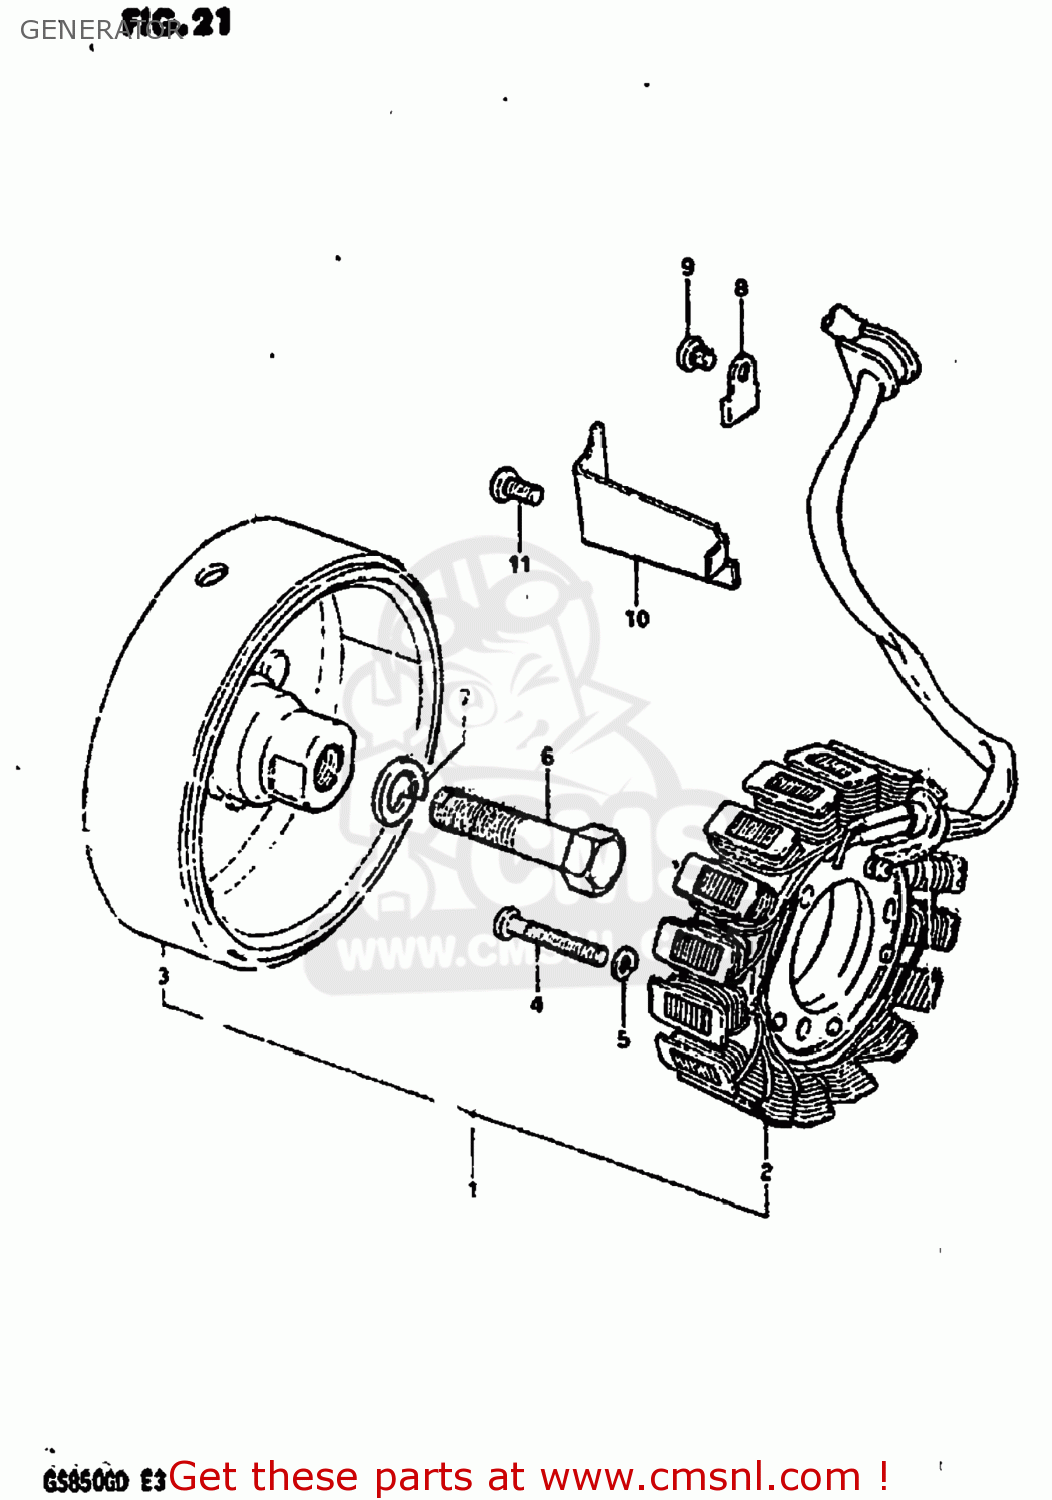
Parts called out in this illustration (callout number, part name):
1	GENERATOR ASSEMBLY
2	STATOR ASSEMBLY
3	ROTOR ASSEMBLY
4	SCREW
5	LOCK WASHER
6	BOLT 12X45
7	WASHER,LOCK 12
8	CLAMP,GENERATOR LEAD WIRE
9	SCREW
10	CLAMP,GENERATOR LEAD WIRE
11	SCREW
